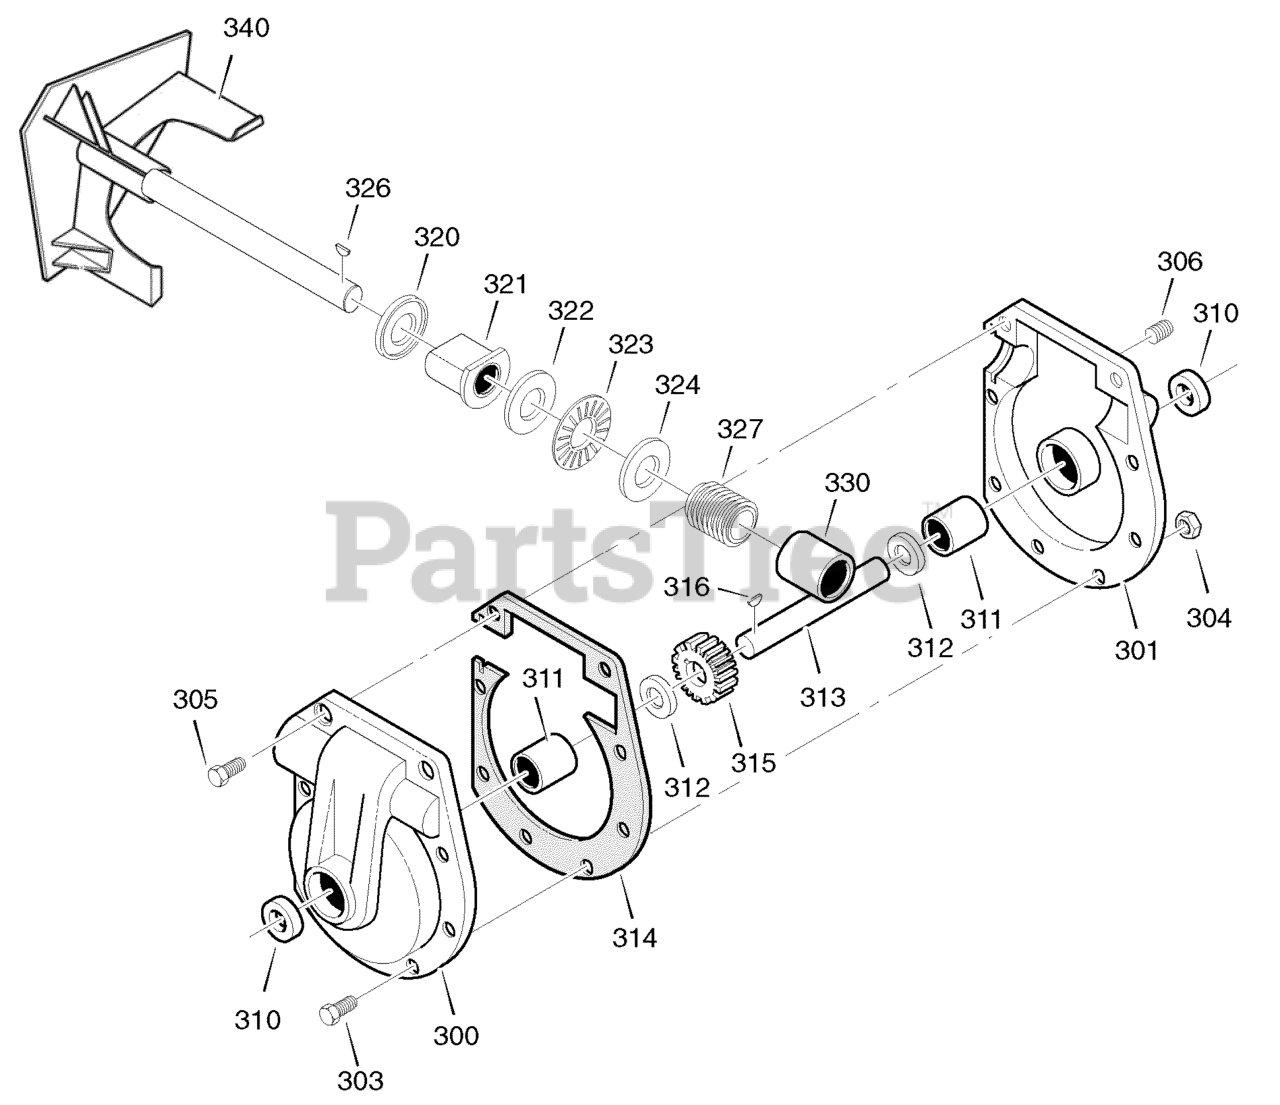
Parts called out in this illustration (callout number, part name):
300	CASE, GEAR, RH
301	CASE, GEAR, LH
303	SCREW, 5/16-24 x 1.00
304	NUT, 5/16-24
305	SCREW, 5/16-24 x 1.50
306	PLUG, PIPE 0.25-18
310	SEAL, OIL
311	BEARING, SLEEVE
312	WASHER, FLAT
313	SHAFT, AUGER OUTPUT
314	GASKET, GEAR BOX
315	WORM GEAR
316	KEY, WOODRUFF #91
320	RING, QUAD 0.924 ID
321	BEARING, FLANGE
322	WASHER, FLAT
323	BEARING, ROLLER
324	WASHER, FLAT
326	KEY
327	WORM
330	BEARING, SLEEVE
